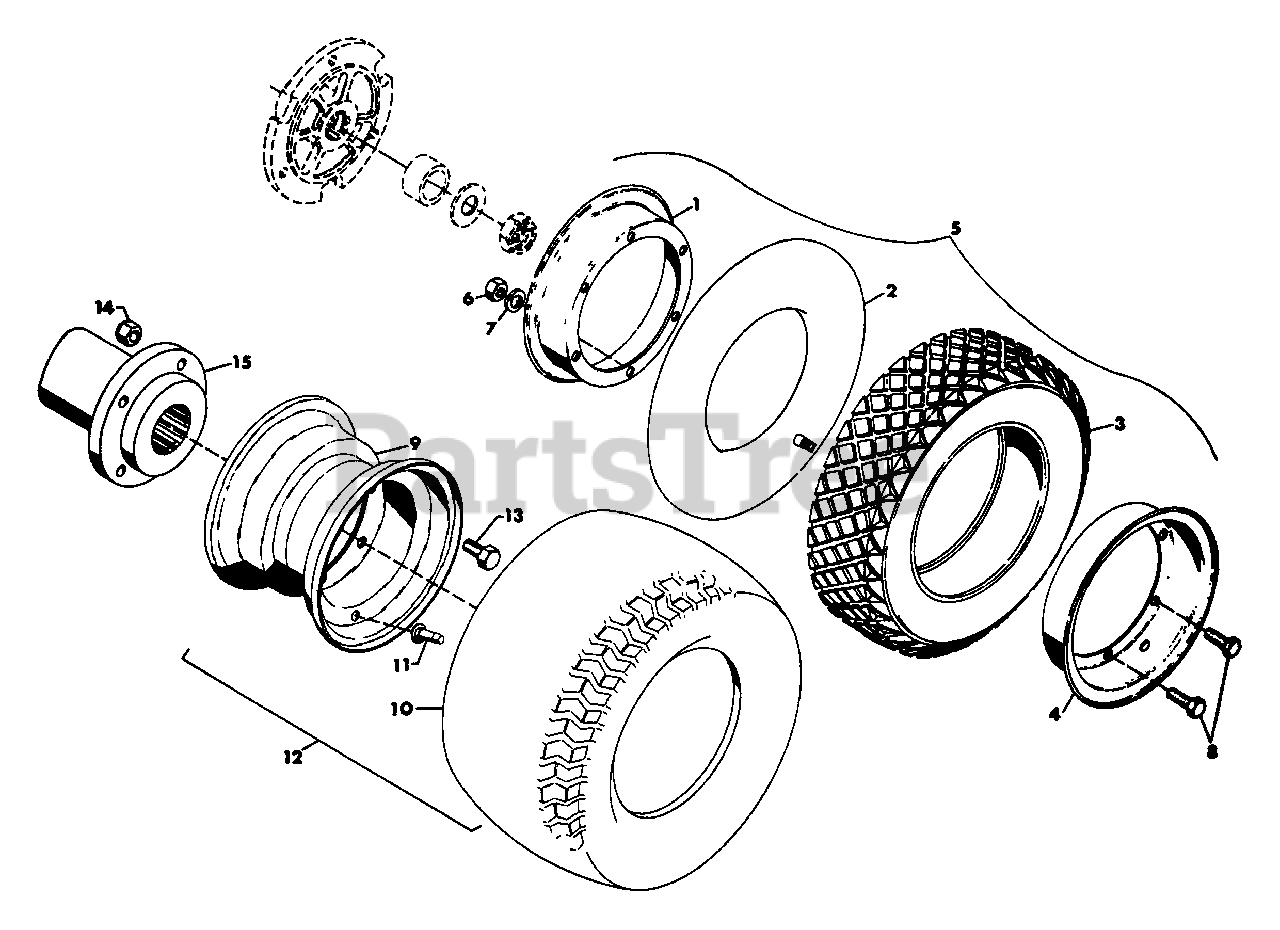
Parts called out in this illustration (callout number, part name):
1	Disc, Inner Wheel
2	Tube, 500 x 8
2	Tube, Tractor Tire
3	Tire, Tractor Diamond Thread 4.80 x 4.00 - 8
3	Tire, Tractor Ground Grip 4.00-8
3	Tire, Semi-Pneumatic 16 x 5W x 3
3	Tire, 18 x 6.50 - 8
4	Disc, Wheel
5	Assembly, Super Grip Wheel 4.00-8
5	Assembly, Diamond Tread Wheel 4.80x4.00-8
5	Tire, Wheel Assembly 18x6.50-8
5	Wheel, Semi-Pneumatic Assembly 16x5Wx3
5	Assembly, Wheel Semi-Pneumatc 19x5
6	Nut, Jam 3/8-16 Hex
7	Washer, Lock 3/8 Reg.
8	Bolt, Hex 3/8-16 x .625
8	Bolt, Hex 3/8-16 x .750
9	Rim, 18x8.50-8
10	Tire, 18x8.50-8
11	Assembly, Valve Stem
12	Assembly, Wheel 18x8.50x8
13	Bolt, Hex 1/2-13 x 1.50
14	Nut, Lock 1/2-13
15	Hub, For 18x8.50x8 Wheel Assembly
